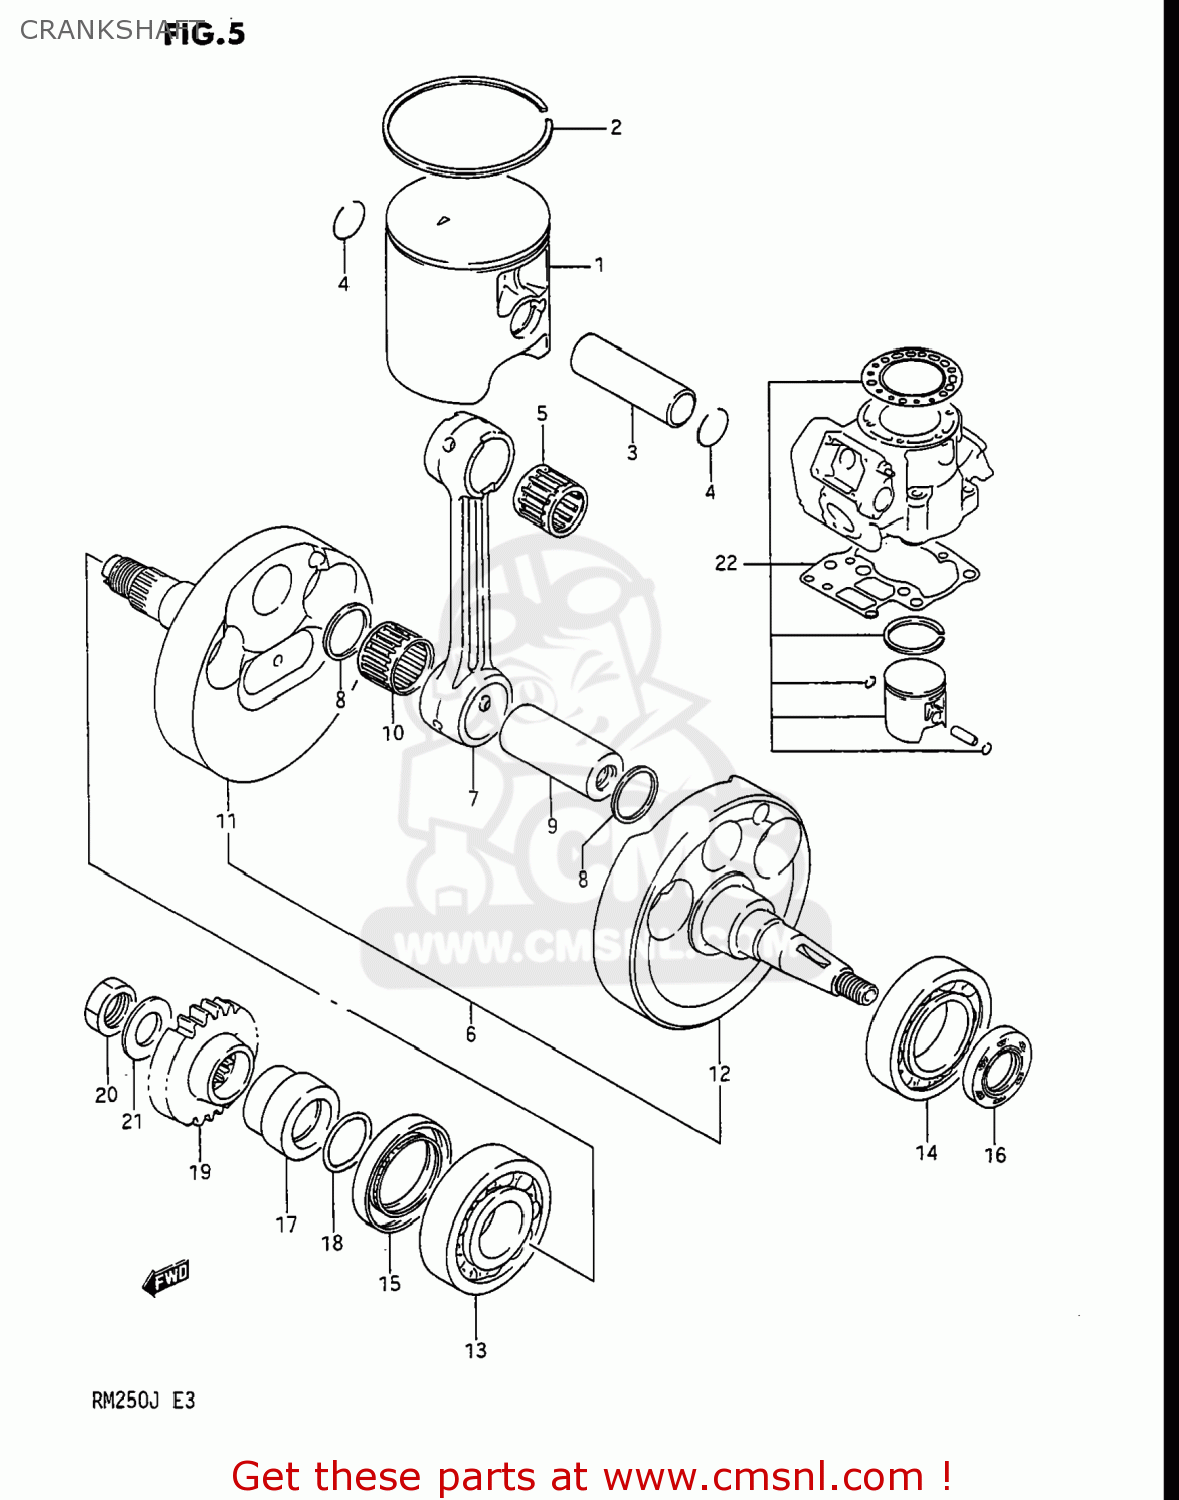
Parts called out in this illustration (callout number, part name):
1	PISTON (67.00MM)
2	RING,PISTON
3	PIN,PISTON
4	CIRCLIP
5	BEARING(18X23X22)
6	CRANKSHAFT ASSEMBLY
7	CONNECTION ROD
8	WASHER(24X29X1.5)
9	PIN COMP,CRANK
10	BEARING
11	CRANKSHAFT,R
12	CRANKSHAFT,LEFT
13	BEARING(25X62X17)
14	BEARING(30X62X16)
15	SEAL,OIL(36X52X8)
16	OIL SEAL
17	SPACER,PRIMARY DRIVE GEAR
18	O RING(D:2.4,ID:21.8)
19	GEAR,PRIMARY DRIVE
20	NUT
21	WASHER
22	PISTON SET (STD)
